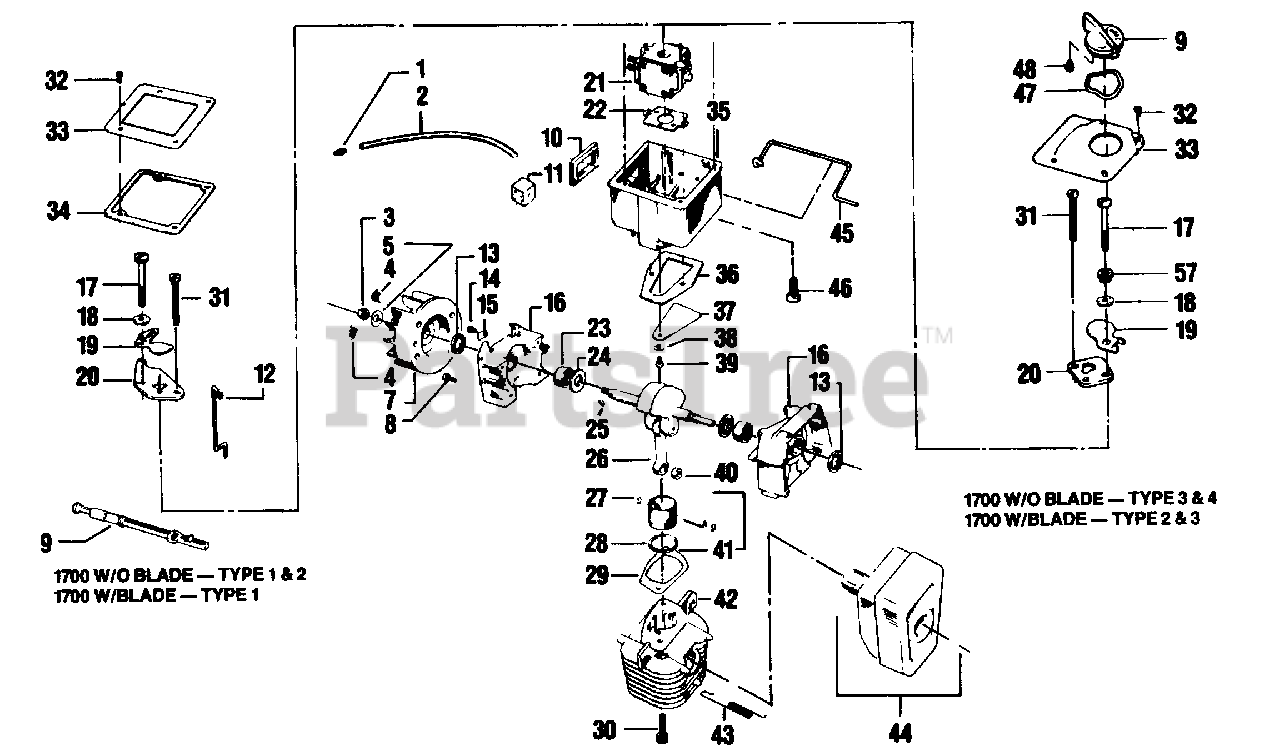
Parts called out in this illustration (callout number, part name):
1	Fuel Line Fitting
1	1700 w/o Blade - Type 1 & 2 1700 w/Blade - Type 1
1	1700 w/o Blade - Type 3 & 4 1700 w/Blade - Type 2 & 3
2	1700 w/o Blade - Type 1 & 2 1700 w/Blade - Type 1
2	1700 w/o Blade - Type 3 & 4 1700 w/Blade - Type 2 & 3
3	Nut - Flywheel (5/16 x 24)
4	Spring - Starter Dog
5	Washer - Flywheel
7	Flywheel Ass'y (Inc. #5)
8	Screw - Crankcase
9	Knob - Choke
9	1700 w/o Blade - Type 1 & 2 1700 w/Blade - Type 1
9	1700 w/o Blade - Type 3 & 4 1700 w/Blade - Type 2 & 3
10	Seal - Carburetor Case
11	Boot - Choke Wire
12	Wire - Choke
12	1700 w/o Blade - Type 2; 1700 w/Blade - Type1
13	Seal - Crankshaft
14	Screw - Clamp
15	Clamp - Choke Wire
16	Crankcase Ass'y (Inc. #13,23 & Qty. 10 of #8)
17	Screw
17	1700 w/o Blade - Type 1 & 2; 1700 w/Blade - Type 1
17	1700 w/o Blade - Type 3 & 4; 1700 w/Blade - Type 2 & 3
18	Wave Washer
19	Shutter - Choke
19	1700 w/o Blade - Type 1 & 2; 1700 w/Blade - Type 1
19	1700 w/o Blade - Type 3 & 4; 1700 w/Blade - Type 2 & 3
20	Guide Plate
20	1700 w/o Blade - Type 2; 1700 w/Blade - Type1
20	1700 w/o Blade - Type 3 & 4; 1700 w/Blade - Type 2 & 3
21	Carburetor (for Type 1) - See Service Ref. 2.
22	Gasket - Carburetor
23	Bearing - Crankshaft
24	Thrust Washer - Crankshaft
25	Key - Flywheel
26	Crankshaft & Rod Ass'y.
26	1700 w/o Blade - Type 1,2 & 3; 1700 w/Blade - Type 1 & 2
26	1700 w/o Blade - Type 4; 1700 w/Blade - Type3
27	Retainer - Wrist Pin
28	Piston Ring
28	1700 w/o Blade - Type 1
28	1700 w/o Blade - Type 2 & 3; 1700 w/Blade - Type 1 & 2
28	1700 w/o Blade - Type 4; 1700 w/Blade - Type 3
29	Gasket - Cylinder
30	Screw - Cylinder (#1/4 - 20 x 3/4" Socket Hd)
31	Screw
31	1700 w/o Blade - Type 1 & 2; 1700 w/Blade - Type 1
31	1700 w/o Blade - Type 3 & 4; 1700 w/Blade - Type 2 & 3
32	Screw - Carburetor Cover - #8 - 18x9/16"
33	Cover - Carburetor Case
33	1700 w/o Blade - Type 1 See Service reference
33	1700 w/o Blade - Type 2; 1700 w/Blade - Type 1
33	1700 w/o Blade - Type 3 & 4; 1700 w/Blade - Type 2 & 3
34	Gasket - Carburetor Case Cover - See Service Ref. 4.
35	Carburetor Case Assembly
36	Gasket - Carburetor Case/Crankcase
37	Reed Valve
38	Washer - Reed Valve
39	Screw - Reed Valve - (#6 - 19 x 5/16")
40	Bearing - Wrist Pin
40	1700 w/o Blade - Type 1,2 & 3; 1700 w/Blade - Type 1 & 2
40	1700 w/o Blade - Type 4; 1700 w/Blade - Type 3
41	Piston Kit
41	1700 w/o Blade - Type 1
41	1700 w/o Blade - Type 2 & 3; 1700 w/Blade - Type 1 & 2
41	1700 w/o Blade - Type 4; 1700 w/Blade - Type 3
42	Cylinder
42	1700 w/o Blade - Type 1
42	1700 w/o Blade - Type 2,3 & 4; 1700 w/Blade - Type 1,2 & 3
42	1700 w/Blade & 1700 w/o Blade
43	Spring - Muffler Attachment
45	Throttle Wire - 1700 w/o Blade - Type 3 & 4; 1700 w/Blade - Type 2 & 3
46	Screw - 1700 w/o Blade - Type 3 & 4; 1700 w/Blade - Type 2 & 3
47	Wave Washer - 1700 w/o Blade - Type 3 & 4; 1700 w/Blade - Type 2 & 3
48	Screw 1700 w/o Blade - Type 3 & 4 1700 w/Blade - Type 2 & 3
57	Spacer - 1700 w/o Blade - Type 3 & 4;
58	Engine Gasket Kit (Inc.10,13,22,29,34,36,)
